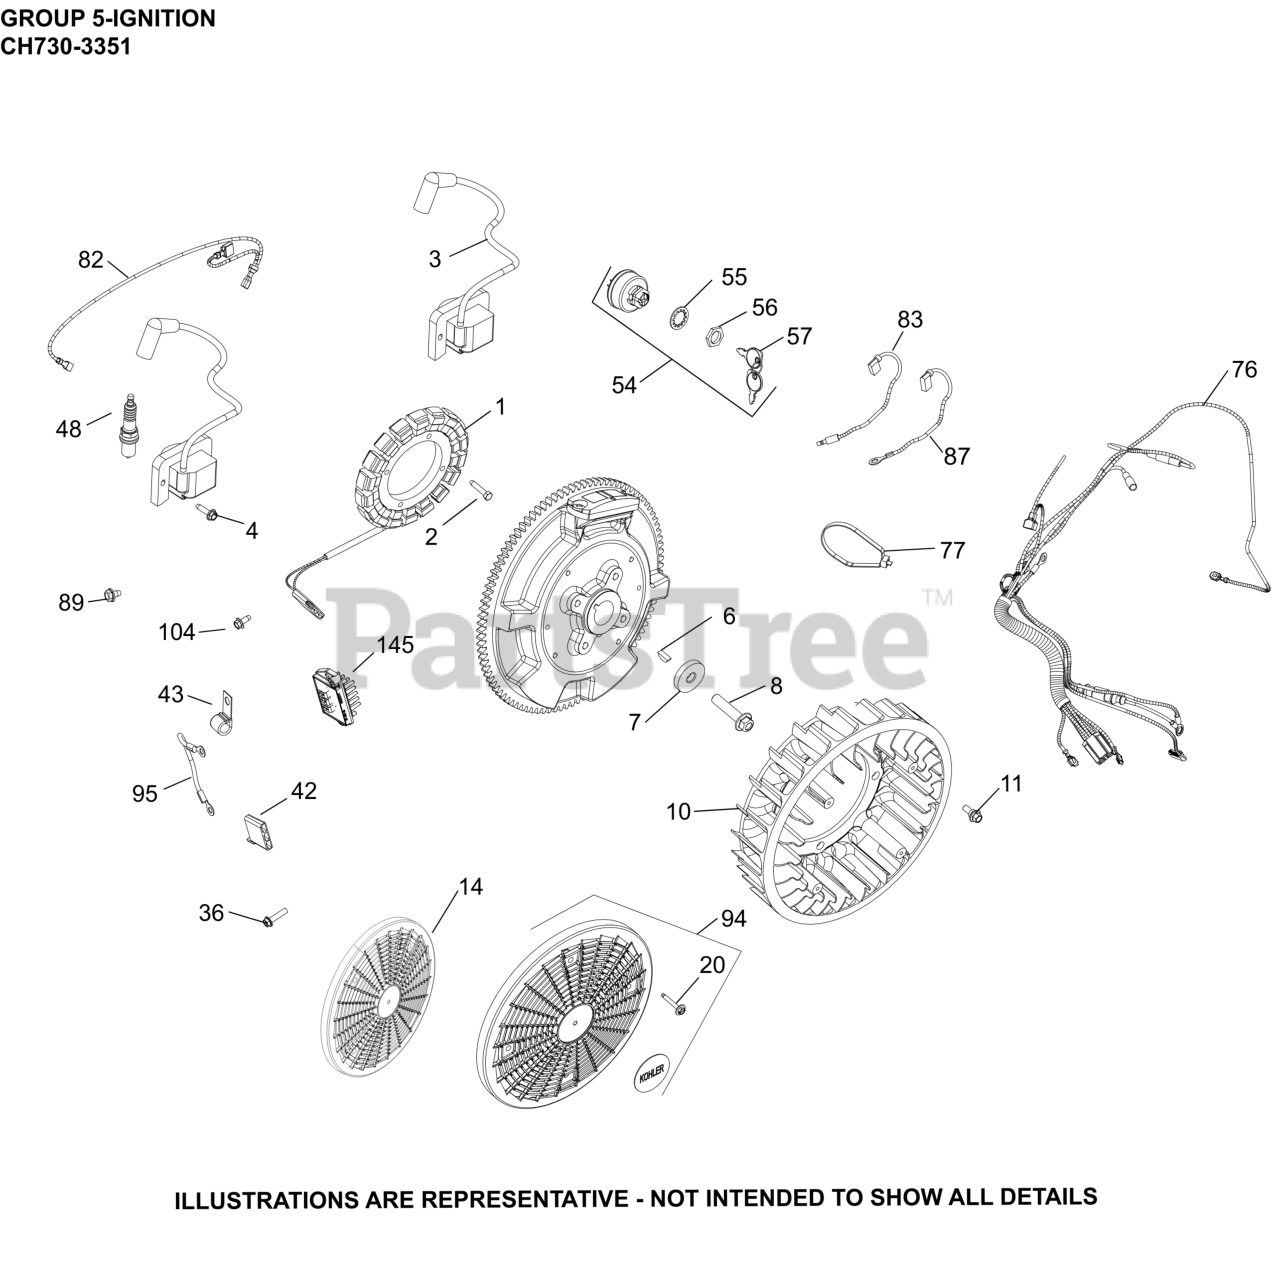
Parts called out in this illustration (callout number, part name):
1	KIT, 15 / 20 AMP STATOR
2	SCREW, THREAD FORMING
3	MODULE, EMC/RFI COMPLIANT
4	SCREW, THREAD FORMING
6	KEY, 3/16" X 5/8"
7	WASHER, FLAT
8	SCREW, HEX FLANGE
10	FAN-USE 24 755 253-S
11	BOLT, SHOULDER
14	SCREEN, GRASS
20	SCREW, FLG SEMS M4x.7x25
36	SCREW, HEX FLANGE HI-LO
42	CONNECTOR
43	CLIP, CABLE
48	SPARK PLUG, RFI
54	KEY ASSEMBLY SWITCH-USE 25 099 37-S
55	WASHER, INTERNAL TOOTH
56	NUT, KEY SWITCH
57	KEY, SET OF 2
76	HARNESS, WIRING ASSEMBLY
82	LEAD, DUPLEX
83	LEAD, OIL SENTRY
87	LEAD, 20/25 AMP B+
89	SCREW, THREAD FORMING
94	KIT GRASS SCREEN
104	SCREW, THREAD FORMING
145	REGULATOR, RECTIFIER (20-30AMP,FW W/OVP)
NI	FLYWHEEL ASSEMBLY (CV/CH670 & 730)
